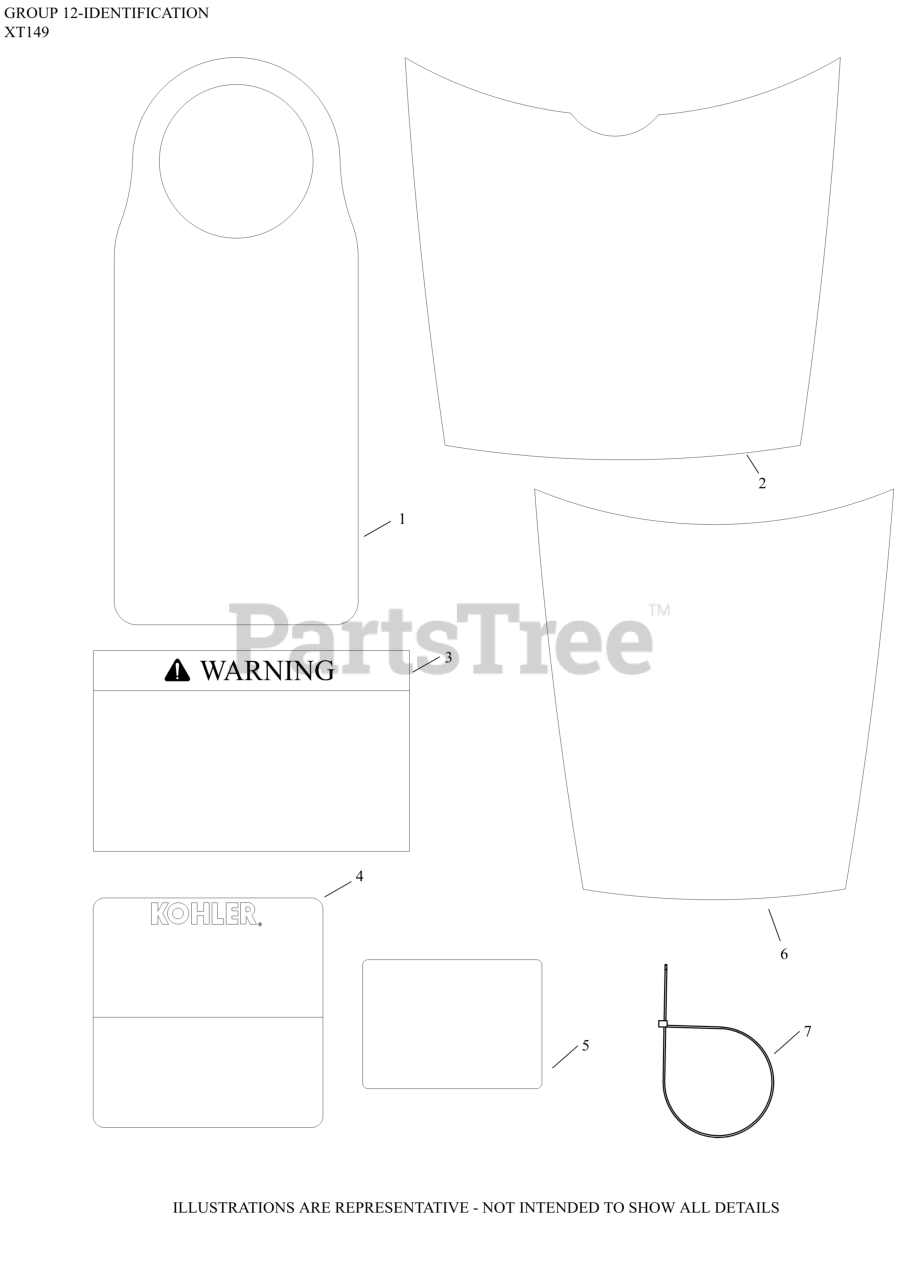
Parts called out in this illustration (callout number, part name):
1	TAG, HANG OIL WARNING
3	DECAL, WARNING
4	NAMEPLATE, SERVICE
